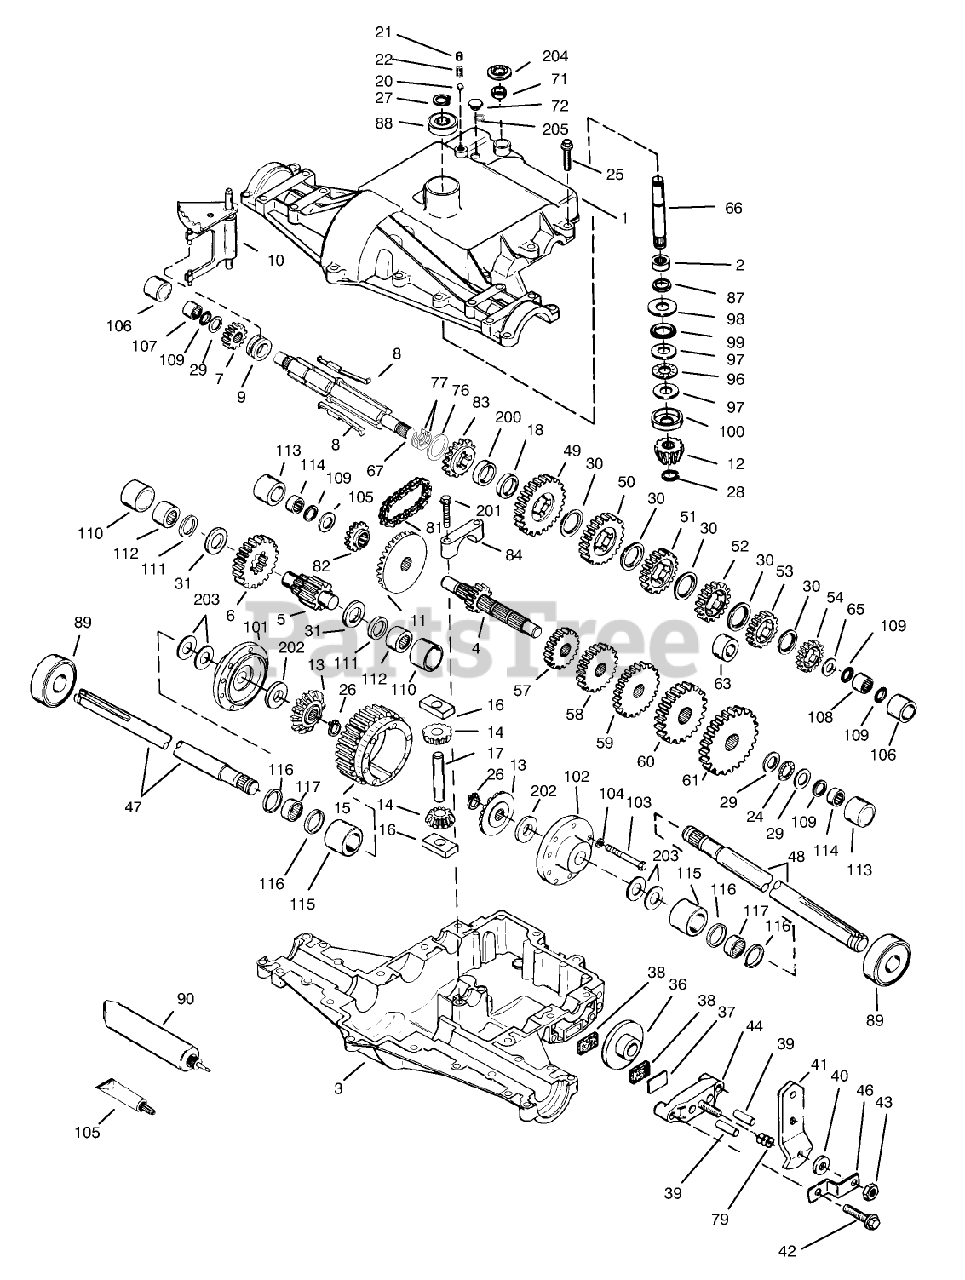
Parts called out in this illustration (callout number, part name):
1	Cover-Transaxle (Only On: 72042, 72062)
2	Bearing-Needle (Only On: 72042, 72062)
3	Case-Transaxle (Only On: 72042,72062)
4	Countershaft-Gear 9t (Only On: 72042, 72062)
5	Shaft-Output (Only On: 72042, 72062)
6	Gear-Output 35t (Only On: 72042,72062)
7	Gear-Spur 15t (Only On: 72042,72062)
8	Key-Shift (Only On: 72042, 72062)
8	Key-Shift (820-024A Only)
9	Collar-Shift
9	Shift Collar
10	Fork-Shift (Only On: 72042,72062)
10	Fork-Shift (820-024A Only)
11	Gear-Bevel 33t (Only On: 72042, 72062)
12	Pinion-Input Bevel 13t (Only On: 72042, 72062)
13	Gear-Bevel
14	Pinion-Bevel
15	Gear-Ring (Only On: 72042,72062)
16	Biock-Drive
17	Pin-Drive
18	Spacer .350-.340 Thick (Only On: 72042, 72062)
20	Ball-Steel
21	Screw-Set
22	Spring
24	Bearing-Thrust
25	Screw 5/16-18x1 1/4
26	Ring-Snap
27	Ring-Snap
28	Ring-Retainer
29	Washer
30	Washer
31	Washer (Only On: 72042,72062)
36	Washer (Only On: 72042, 72062)
37	Brake Pad Plate
38	Pad-Brake 2/Pkg
39	Dowel Pin
40	Washer
41	Lever-Brake
42	Ring Set (.020 O S)
43	Locknut
44	Nozzle-Carburetor
46	Bracket
47	Axle 12 9/16" Long (Only On: 72042,72062)
48	Axle 16 7/16" Long (Only On: 72042, 72062)
49	Gear-Spur 41t (Only On: 72042,72062)
50	Gear-Spur 35t (Only On: 72042,72062)
51	Gear-Spur 30t (Only On: 72042, 72062)
52	Gear Spur 25t (Only On: 72042,72062)
53	Gear Spur 22t (Only On: 72042,72062)
54	Gear Spur 19t
57	Gear Spur 15t (Only On: 72042, 72062)
58	Gear Spur 20t (Only On: 72042, 72062)
59	Gear Spur 25t (Only On: 72042, 72062)
60	Gear Spur 28t (Only On: 72042,72062)
61	Gear Spur 30t (Only On: 72042,72062)
65	Washer
66	Shaft-Input 30.910" Lg (Only On: 72042, 72062)
67	Shaft-Shifter/Brake (Only On: 72042, 72062)
67	Shaft-Shifter/Brake (820-024A Only)
71	Cut Seal-Square
72	Plug-Threaded 5/16-18
76	Washer
77	Inverted Retaining Ring
79	Piston ASM (.020 O S)
81	Chain-Roller
82	Sprocket 10t
83	Sprocket (14 teeth)
84	Cap-Bearing (Only On: 72042, 72062)
87	Seal Oil
88	Bearing-Ball
89	Bearing-Ball
90	Grease 32 Oz
96	Bearing-Thrust (Only On: 72042,72062)
97	Washer
98	Washer (Only On: 72042, 72062)
99	O Ring (Only On: 72042,72062)
100	Washer-Cupped (Only On: 72042,72062)
101	Carrier-Differential (Only On: 72042, 72062)
102	Carrier-Differential (Only On: 72042, 72062)
103	Screw-Hex Hd.
104	Lockwasher
105	Washer (Only On: 72042,72062)
106	Sleeve (Only On: 72042,72062)
107	Bearing-Needle (Only On: 72042,72062)
108	Bearing-Needle (Only On: 72042, 72062)
109	O Ring
110	Sleeve (Only On: 72042, 72062)
111	Ring-Square Cut (Only On: 72042, 72062)
112	Bearing-Needle (Only On: 72042, 72062)
113	Sleeve (Only On: 72042, 72062)
114	Bearing-Needle (Only On: 72042,72062)
115	Sleeve (Only On: 72042,72062)
116	Ring-Square Cut (Only On: 72042,72062)
117	Bearing-Needle (Only On: 72042,72062)
150	Gasket Eliminator
200	Spacer .276-.268 Thick (Only On: 72042, 72062)
201	Ring Set (.020 O S)
202	Washer
203	Washer
204	Pushnut
205	O Ring
